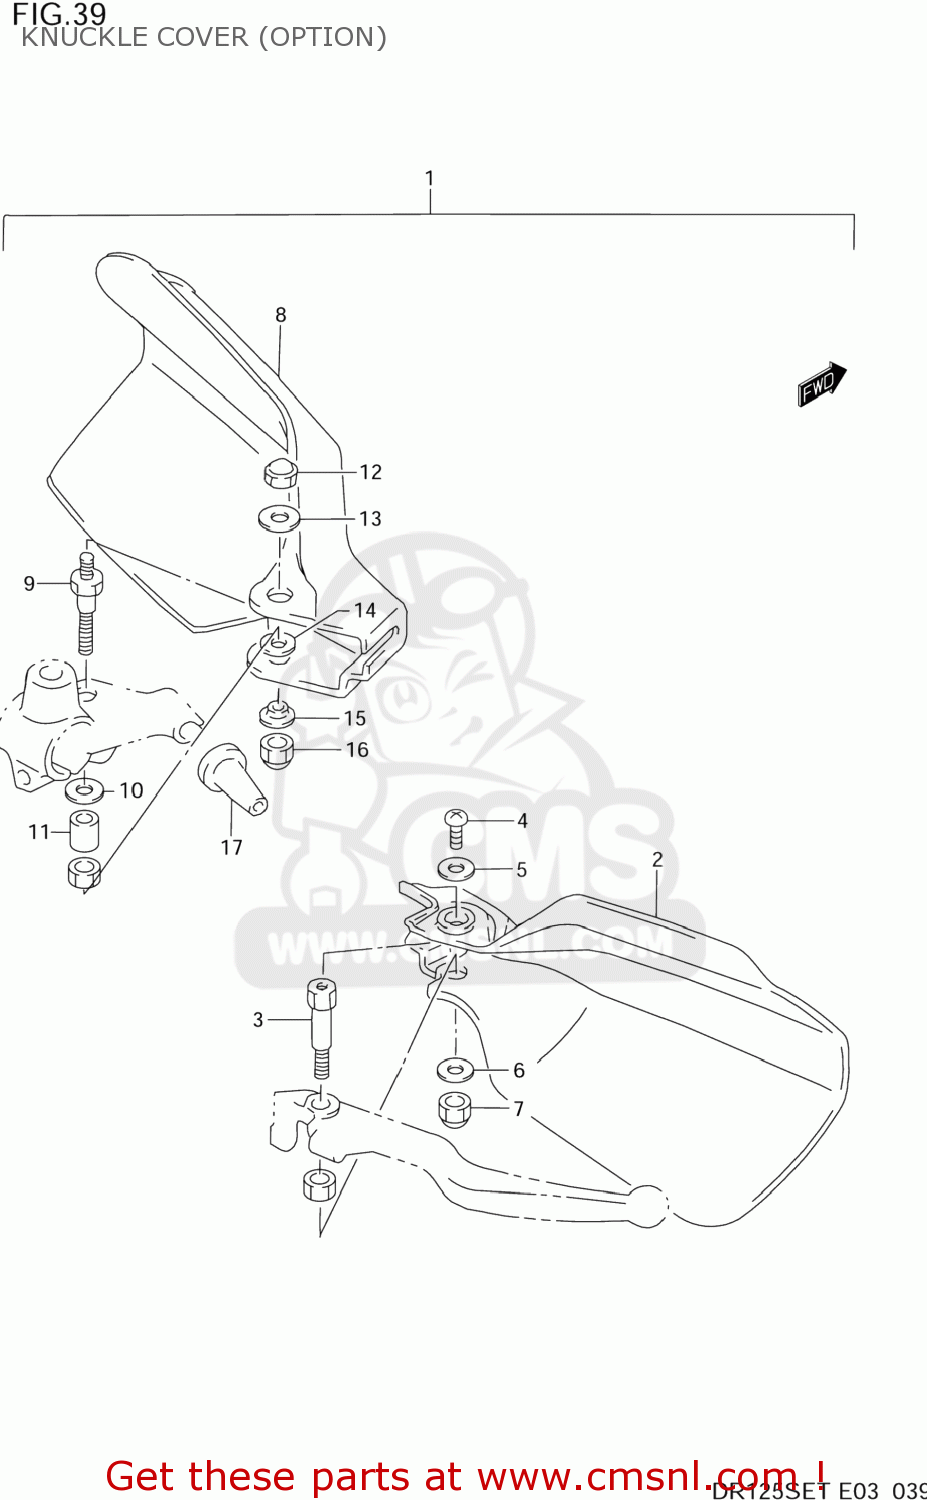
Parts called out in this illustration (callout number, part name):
1	COVER SET,KNUCKLE
2	COVER,KNUCKLE,R
3	BOLT,BRAKE LEVER PIVOT
4	SCREW
5	WASHER (5.5X16X1.2)
6	WASHER (6.5X17X1.6)
7	NUT 6MM
8	COVER,KNUCKLE,LEFT
9	BOLT,LEVER SET
10	WASHER,LEVER SET
11	SPACER,LEVER SET
12	NUT
13	WASHER(6.5X20X1.6)
14	WASHER(6.5X16X1.2)
15	WASHER
16	NUT 6MM
17	BOOT,CLUTCH CABLE
